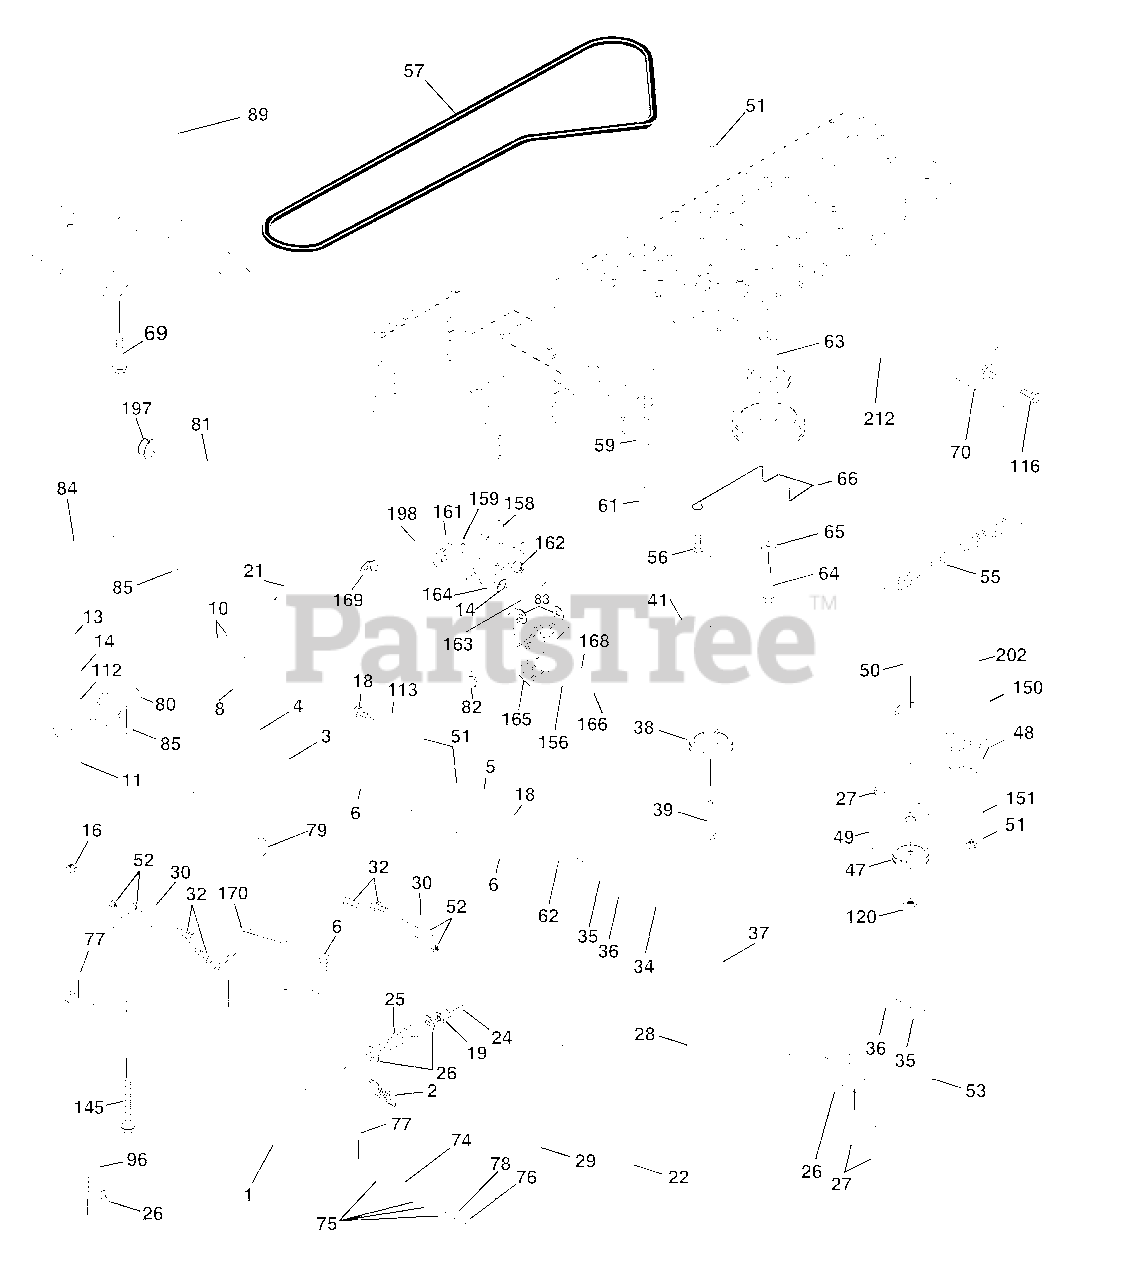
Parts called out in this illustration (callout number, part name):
1	Transaxle
2	Spring Return Brake T/a Zinc
3	Pulley Transaxle 18" tires
4	Ring Retainer # 5100-62
5	Strap Torque 30 Degrees
6	Screw 5/16-18 X 3/4
8	Rod Shifter Fender Adj Lt
10	Pin Cotter 1/8 X 1 Cad
11	Washer Plate Shf 388 Sq Hole
13	Bolt 1/4-28 Unf Gr 8 W/Patch
14	Washer Lock Hvy Helical 1/4
16	Nut Lock Hx W/Ins 5/16-18 Unc
18	Bolt, Fin Hex 3/8-16 UNC x 1 Gr. 5
19	Nut Lock 3/8-16 Unc
21	Knob
22	Rod Brake Blk Zinc 26 840
24	Nut Hex Jam 3/8-16 Unc
25	Spring Rod Brake 2 00 Zinc
26	Washer 13/32 X 13/16 X 16 Ga
27	Pin Cotter 1/8 X 3/4 Cad
28	Rod Brake Parking LT/YT
29	Cap Brake Parking
30	Bracket Mtg Transaxle
32	Bolt Hex Hd 5/16-18unc X 3/4
34	Shaft Asm Pedal Foot
35	Bearing Nylon Blk 629 Id
36	Washer 21/32 X 1 X 16 Ga
37	Pin Roll 3/16 X 1"
38	Pulley Idler Composite
39	Bolt Fin Hex 3/8-16 X 3
41	Keeper Belt Idler
47	Pulley Idler V Groove Plastic
48	Bellcrank Asm
49	Retainer Belt Style Spring
50	Bolt Hex Hd 3/8-16unc X 1-1/2
51	Nut Crownlock 3/8-16 Unc
52	Nut Crownlock 5/16-18 Unc
53	Link Clutch
55	Spring Return Clutch 6 75
56	Screw 3/8-16 X 1-1/4
57	V-Belt Ground Drive
59	Keeper Belt Span Ctr
61	Screw 3/8-16 x .875
62	Cover Pedal Blk Round
63	Engine Pulley LT/YT
64	Bolt Hex
65	Washer Lock Hvy Hlcl Spr 7/16
66	Keeper Belt Engine Foolproof
69	Screw Hex Wsh Hi-Lo 1/4-1/2 Unc
70	Guide Belt Mower Drive RH
74	Spacer Axle
75	Washer 25/32 X 1 1/4 X 16 Ga
76	E-ring #5133-75
77	Key Square 2 0 X 1845/ 1865
78	Washer 25/32 X 1-5/8 X 16 Ga
79	Key Woodruff
80	Arm Shift
81	Shaft Asm Cross Tapered 20"t
82	Spring Torsion T/a
83	Washer 17/32 X 3/4 X 16 Ga
84	Link Transaxle
85	Nut Lock Center 1/4 - 28 FNTHD
89	Console Shift STLT
96	Retainer Spring
112	Washer 9/32 x 3/4 x 10 Ga.
113	Strap Torque Lh
116	Bolt Rdhd Sq Neck 3/8-16 x 1
120	Nut Lock Flg 3/8-16
145	Bolt Hex 5/16-18 Gr. 5
150	Spacer Retainer
151	Washer 13/32 x 2 x 10
156	Washer Srrted 5/16 ID x 1.125
158	Bracket Shift Mount
159	Hub Tapered Flange Shift lt
161	Bolt Rdhd Sqnk 1/4-20 x 3/4 Gr 5
162	Nut Crownlock 1/4-20 Unc
163	Bolt Hex Fin 1/4-20 Unc x 1 Gr 5
164	Washer 5/8 x .281 x 10 Ga
165	Bracket Pivot Lever
166	Screw 5/16-18 x 5/8
168	Bolt Shoulder 5/16-18 x .561
169	Plate Fastening Lt
170	Keeper Belt Transaxle
197	Nyliner Snap-In
198	Washer Nyliner
202	Bolt Carr. Sh 3/8-16 x 1-3/4 Gr. 5
212	Nut Hex Flange Lock
